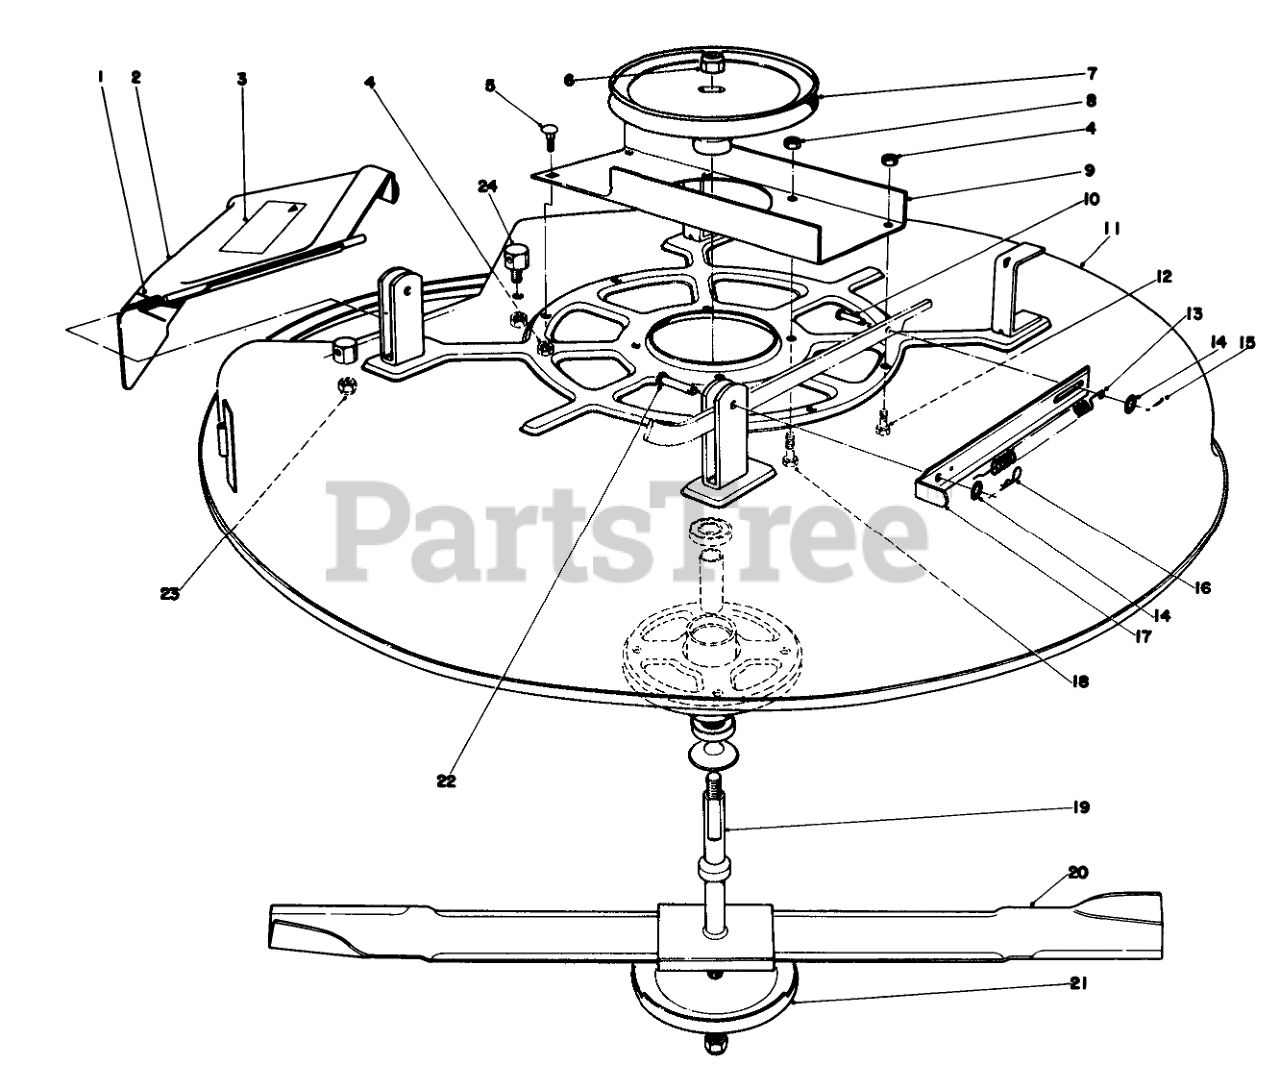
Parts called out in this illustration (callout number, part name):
1	SPRING
2	Deflector Assembly (Incl. Ref. #3)
3	Decal
4	NUT-HEX, SIDE DEFORM
5	SCREW-CARR
7	BLADE DRIVE PULLEY
8	NUT-LOCK, CONE
9	REINFORCEMENT CHANNEL
10	PIN-CLEVIS
11	Cutter Deck
12	SCREW-HH
13	DECK TENSION SPRNG O
14	WASHER-FLAT
15	PIN-COTTER
16	PIN-COTTER
17	Strap-Deck Spring
18	SCREW-HH
19	Spindle Assembly
20	Blade
21	Cup
22	PIN-CLEVIS
23	NUT-LOCK, SIDE
24	POST-PIVOT
